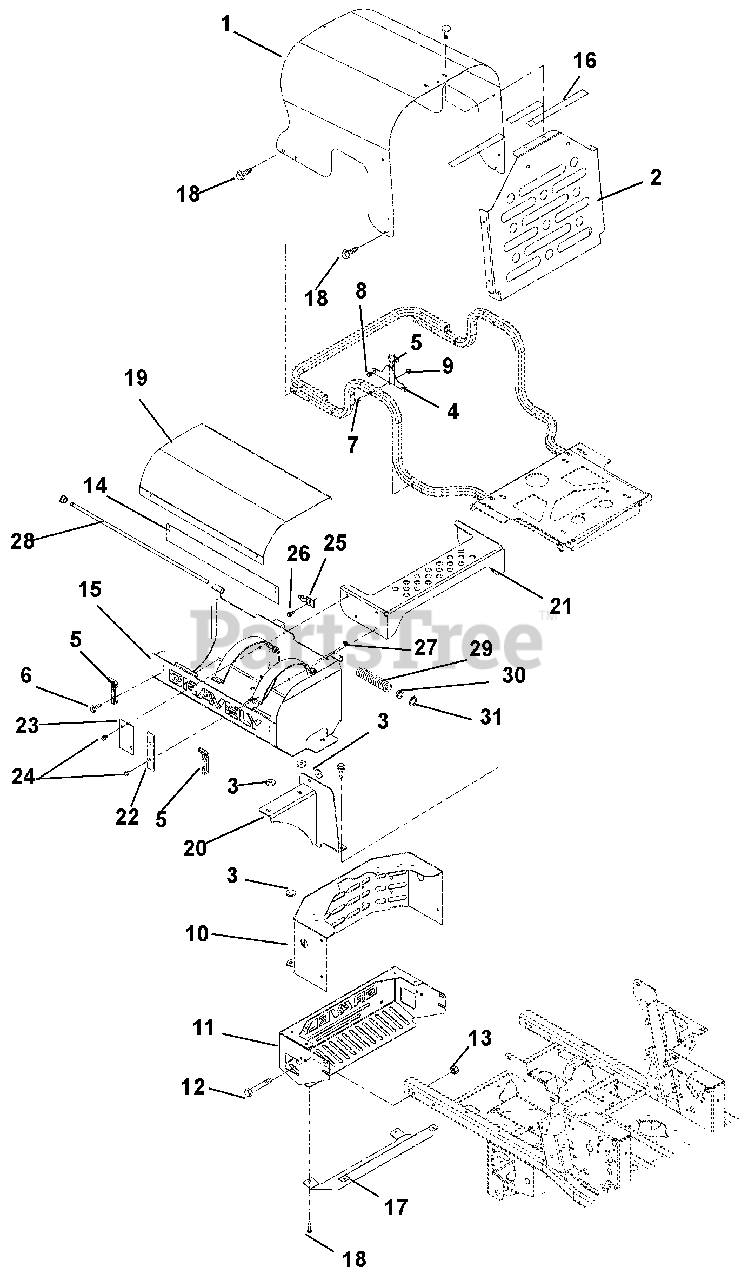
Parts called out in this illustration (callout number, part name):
1	Hood, 200 XDZ LPG
2	Shroud, Hood
3	Washer, Flat Steel .406 x 1.50 x .245
4	Bracket, Latch Stop
5	Latch, Rubber
6	Screw, Machine 10-24 x .50 Hex Washer Head
7	Screw, Machine 10-24 x 1.50 Hex Washer Head
8	Button Bumper
9	Nut, Spin Lock Flange .312-18
10	Guard, Rear Engine 200 XDZ LPG
11	Bumper, Rear
12	Bolt, Hex .38-16 x 2.75 Grade 5
13	Nut, Locking Top Flange .38-16
14	Plate, Name Backer LPG
15	Weldment, Tank Housing Right Hand
15	Weldment, Tank Housing Left Hand
16	VHB Tape 4941F
17	Heat Shield
18	Screw, Tapping .38-16 x .50 Hex Washer Head Thread Rolling YWZ
19	Weldment, Cover Tank Right Hand LPG
19	Weldment, Cover Tank Left Hand LPG
20	Weldment, Right Hand Tank Support
20	Weldment, Left Hand Tank Support
21	Weldment, Tank Support
22	Plate, LPG Tank Support Backer
23	Plate, LPG Tank Support Backer
24	Bolt, Round Head Square neck .38-16 x 1.25
25	Thumb Latch
26	Screw, Machine 10-24 x .50 Hex Washer Head
27	Nut, Locking Nylon 10-24 with Insert
28	Rod, Tank Cover Hinge LPG
29	Spring, Compression .06 ID x 9.5
30	Bushing, Flange
31	Ring, Retaining External .500 x .050
